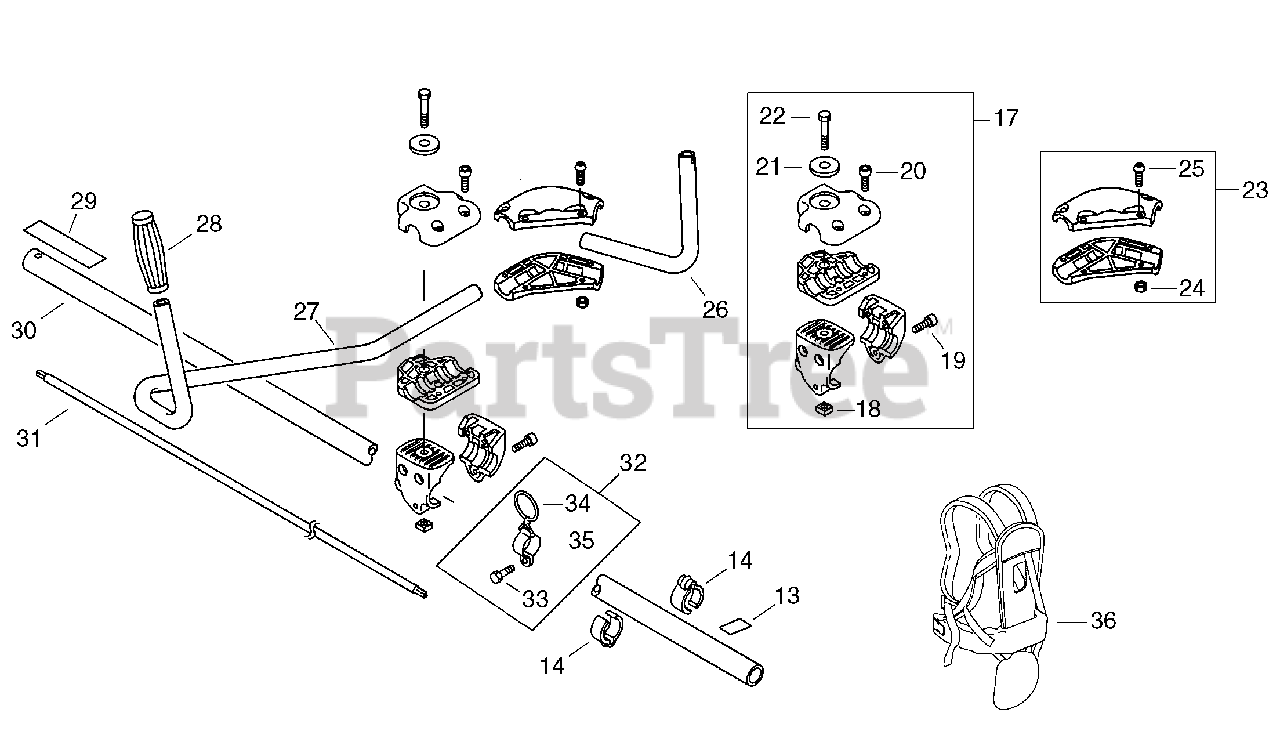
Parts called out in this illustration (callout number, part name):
13	LABEL - ALIGNMENT
14	CLIP 28 MM
17	MOUNT KIT, HANDLE
18	NUT 8×1.25
19	BOLT 5×30
20	BOLT 5×20
21	WASHER 8
22	BOLT 8×55
23	BRACKET KIT, HANDLEBAR
24	NUT M5
25	BOLT 5×22
26	HANDLEBAR, RIGHT
27	HANDLEBAR, LEFT
28	GRIP, HANDLE
29	LABEL, CAUTION - ISO
30	MAIN PIPE ASSY 28×1530
31	DRIVESHAFT
32	HANGER ASSY, HARNESS
33	BOLT 5×12
34	RING, HARNESS
35	HANGER, HARNESS
36	HARNESS, BRUSHCUTTER
